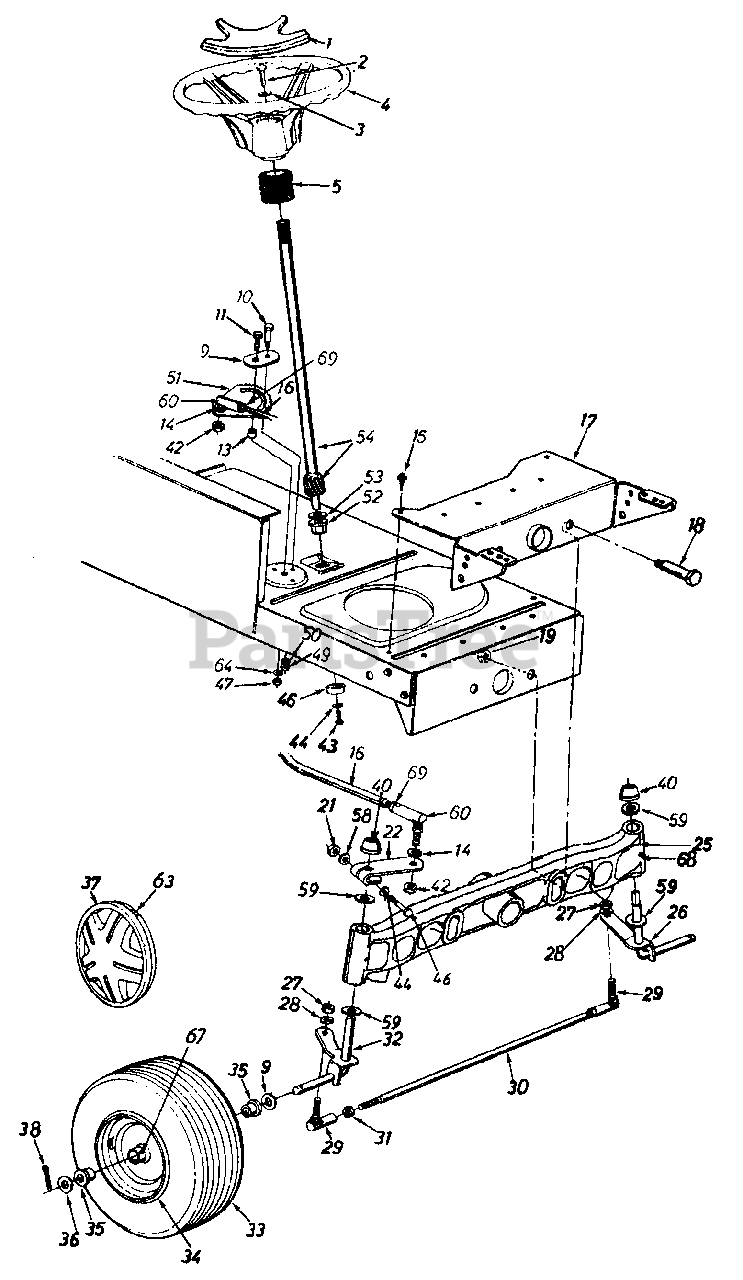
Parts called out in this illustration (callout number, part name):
1	Steering Wheel Cap
2	Hex Bolt 5/16-18 x 1" Lg.
3	Belleville Wash. .345" I.D.
4	Steering Wheel
5	Steering Bellow - 9"
9	Retainer Plate
10	Shoulder Bolt .437" Dia. x .35" Lg.- 5/16-18 Thd.
11	Hex Bolt 3/8-24 x 1.0" Lg. (Grade 5)
13	Spacer .380" I.D. x .625" O.D. x .227
14	L-Wash. 3/8" I.D. (H.D.)
15	Hex Wash. Nd. Self-Tap Scr.
16	Steering Drag Link
18	Shoulder Bolt .498" Dia. x 2.04" Lg.- 3/8-16 Thd.
19	Flanged Hex Nut 3/8-16 Thd.
21	Hex L-Nut 5/16-24 Thd.
22	Steering Arm Front Axle
25	Pivot Bar Ass'y.
26	Front Axle Ass'y.- L.H.
27	Hex Nut 3/8-24 Thd.
28	L-Wash. 3/8" I.D.
29	Ball Joint 3/8-24 Thd.
31	Hex Jam Nut 3/8-24 Thd.
32	Front Axle Ass'y.- R.H.
36	Fl-Wash. .635" I.D. x 1.59" O.D.
37	Hub Cap
38	Cotter Pin 1/8" Dia. x 1.25"
40	Push Cap 5/8" Dia. Rod
42	Hex Jam Nut 3/8-24 Thd.
43	Torx Bolt 5/16-18 x .63" Lg.
44	L-Wash. 5/16" I.D.
46	Cap
47	Hex Cent. L-Nut 3/8-24 Thd.
49	Hex Cent. L-Nut 5/16-18 Thd.
50	L-Wash. 5/16" I.D.
51	Steering Gear Segment
52	Hex . Flg. Brg. 5/8" I.D.
53	Fl-Wash. (Hardened)
54	Steering Shaft
58	Wave-Wash. .32" I.D. x .62" O.D
59	Fl-Wash. (Hardened)
60	Drag Link Ball Joint 7/16-20 Thd.
63	Spring Clip
64	Bell-Wash. .39" I.D. x 1.38" O.D.
67	Grease Fitting
68	Grease Fitting
69	Hex Jam Nut 7/16-20 Thd.
